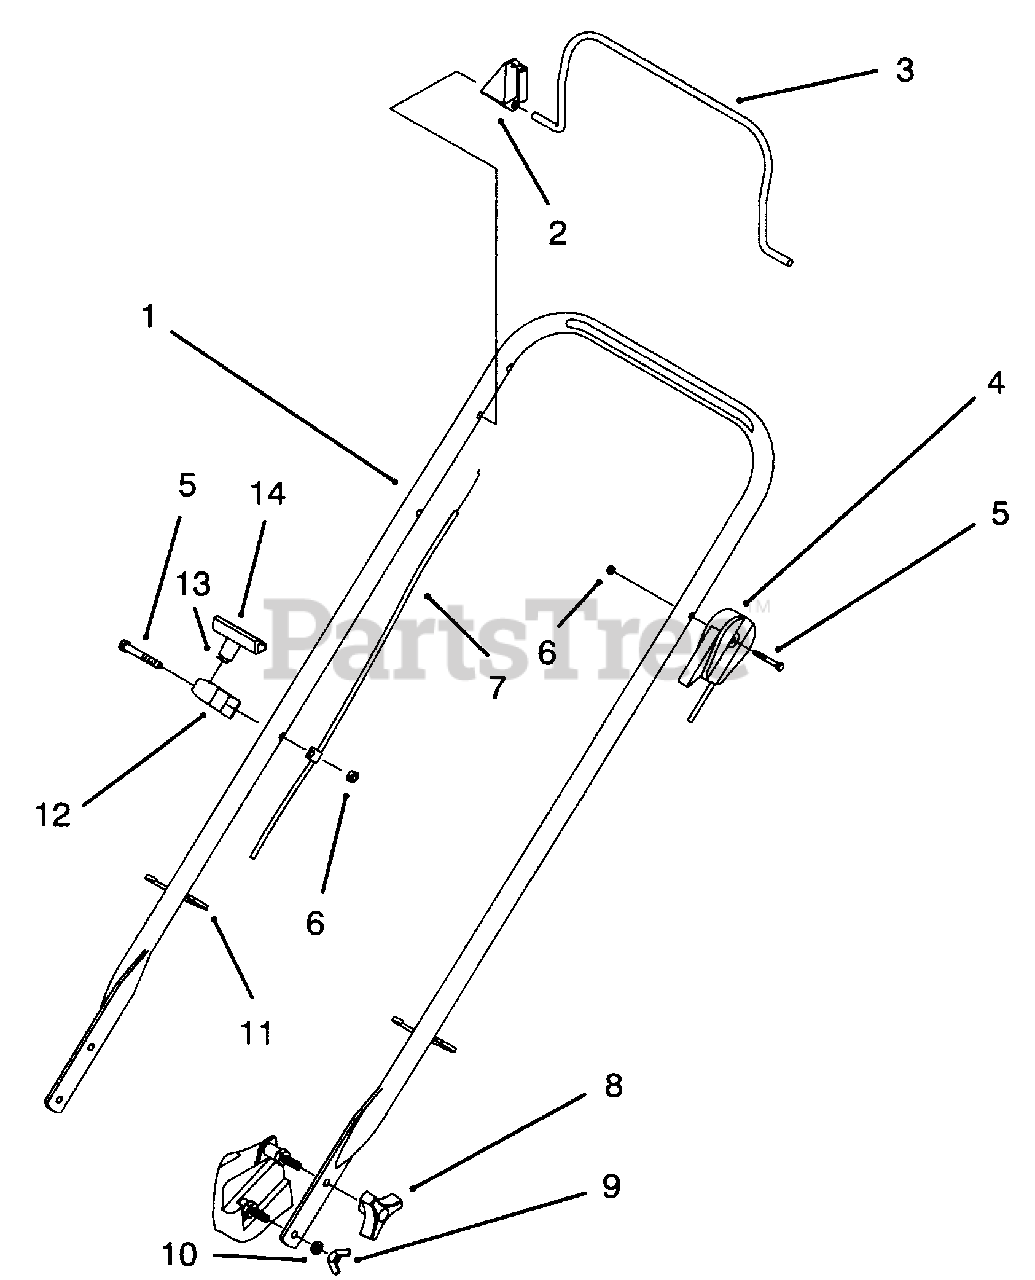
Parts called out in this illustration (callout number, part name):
2	Stop-Pivot
3	Bail-Flywheel Brake
4	Cable-Throttle
5	Screw-Hex Hd. Cap
6	Nut-Lock
7	Cable-Brake
8	Knob
10	Washer-Lock
11	Tie-Cable
12	Guide-Rope
13	Handle-Starter
14	Clip-Rope Insert
